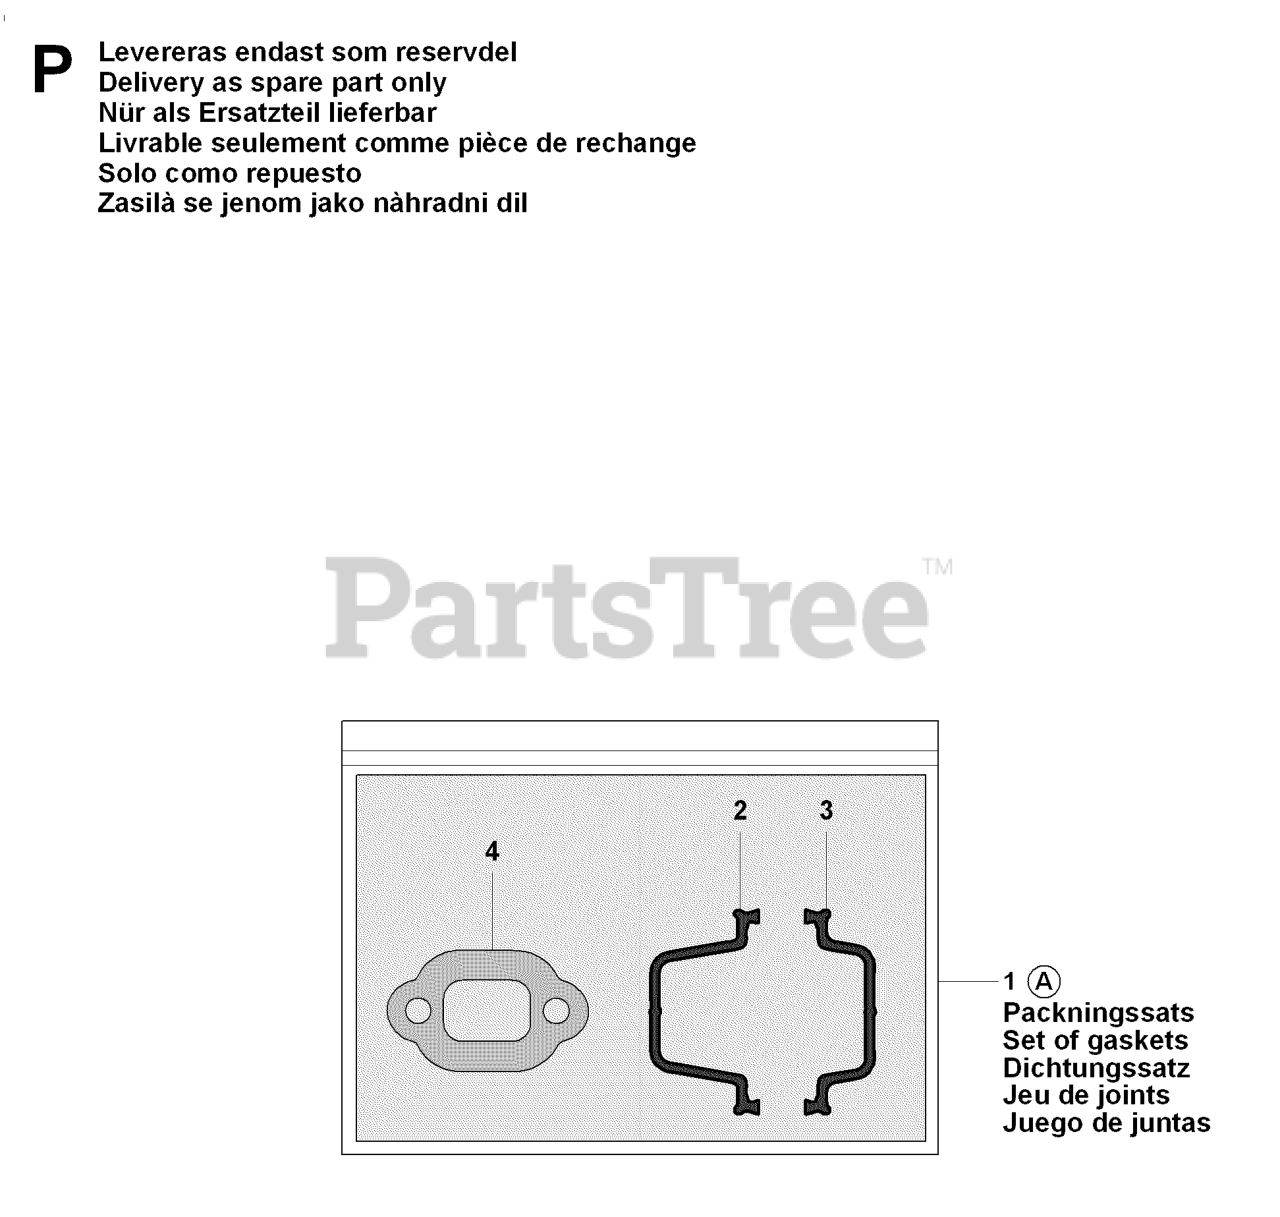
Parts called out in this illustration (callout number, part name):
1	GASKET SET
2	GASKET
3	GASKET
4	RP GASKET
